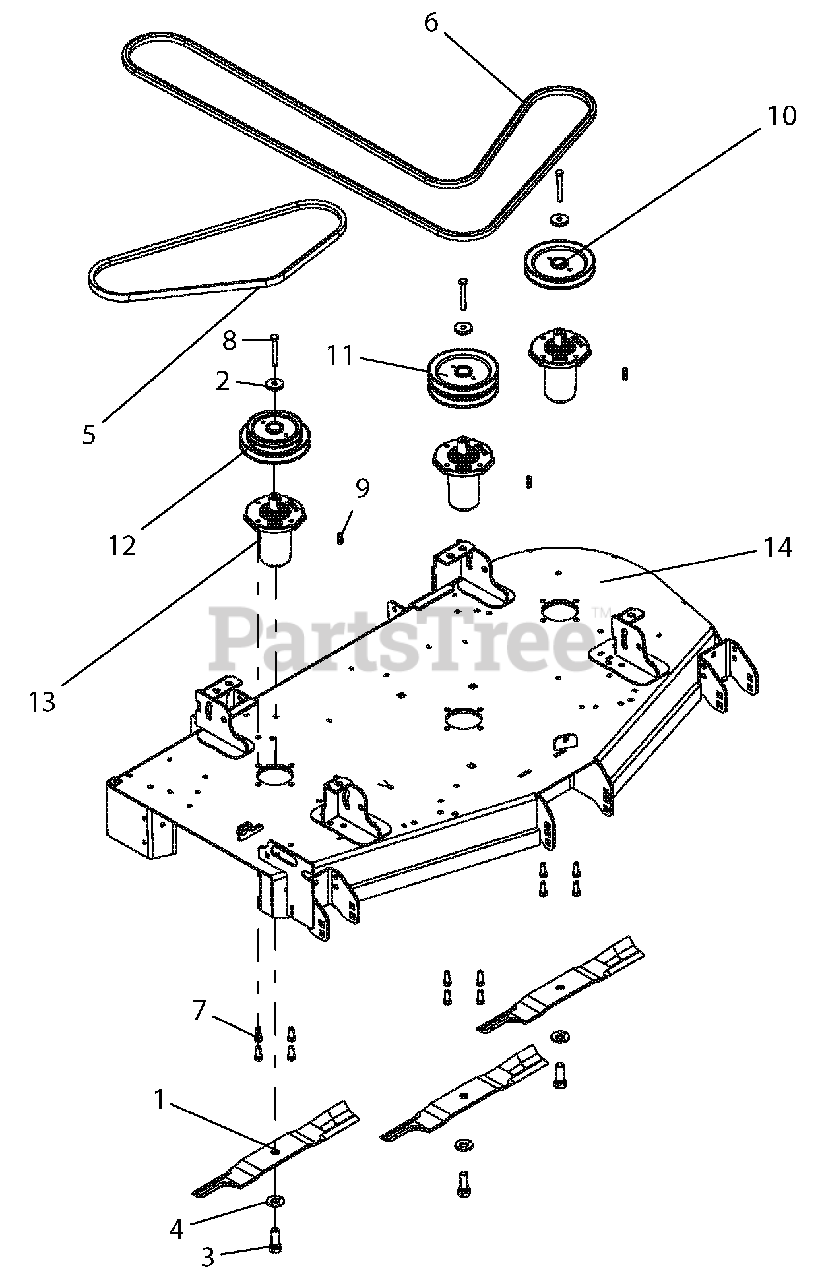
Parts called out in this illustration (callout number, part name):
1	BLADE, 18.00" MOVER (HI-LIFT)
2	RETAINER, SHEAVE SPINDLE
3	BLT, HEX .62-18X1.75 GR8 YWZC
4	WSHR, BLVL .63X1.625X.14
5	BELT, B 56.00 RAW COGGED
6	BELT, BB 118.00 WRAPPED HEX
7	BLT-HEX .38-16X1.00 GR5 YWZC EP30
8	BLT-HEX .38-16X2.75 GR8 YWZC
9	KEY-SQ .250X.250X1.00 RC 40-50
10	PULLEY, SINGLE -1" ID X 6.00" OD-BLACK
11	PULLEY, DOUBLE -1" ID X 6.00" OD-BLACK
12	PULLEY, DOUBLE -1" ID X 6.00" & 4.75" OD
13	SERVICE, ASM SPINDLE- DUCTILE
14	WLDMT, 52" PT200 SIDE DISCHARGE DECK-RED
